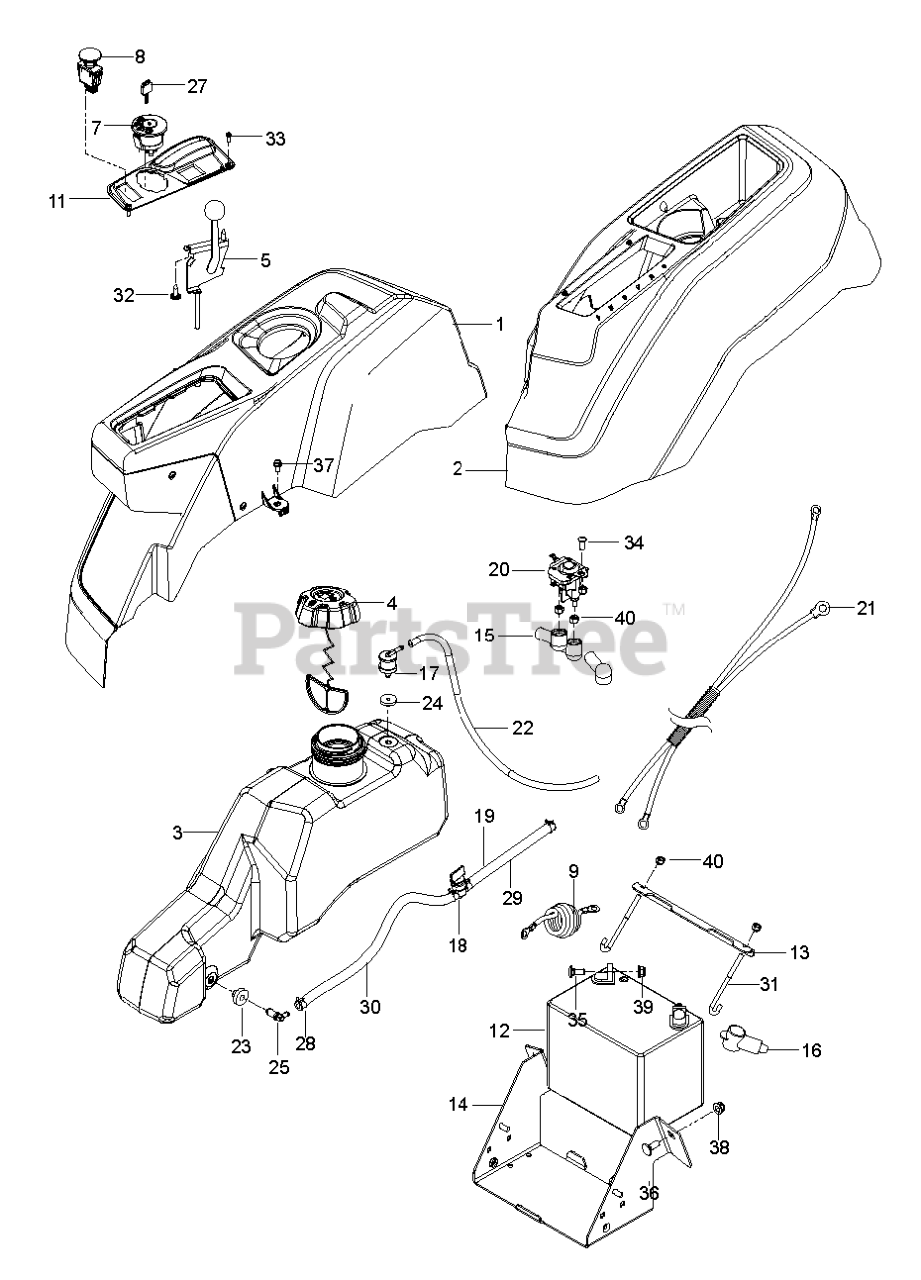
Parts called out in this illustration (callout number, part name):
1	CONSOLE ASM
2	CONSOLE ASM
3	TANK.ASM3"NECK.NOCAP.NOSHDRZ18
4	CAP ASSY FUEL 3" GRAY
5	CABLE.THROTTLE.20"
7	RP IGNITION SWITCH
8	RP SWITCH.PTO.TERMINAL.STD.RED
9	CABLE BATTERY POS RZ
12	BATTERY 12 VOLT 25 AMP
13	BRACKET.PNT.MOUNT.BATTERY.EDIP
14	BOX.PNT.BATTERY.RZ.EDIP
15	TERMINAL COVER
17	VALVE.FUEL.CHECK
18	FUEL VALVE
19	FUEL.HOSE.SHUT.OFF.ASM.10".3"
20	SOLENOID.STARTER.BRASS.PLUNGER
21	HARNESS.BTTRY.CABLE.RZ.REFRESH
22	HOSE.3/16".VAPOR.LINE.18"LGTH
23	BUSHING OUTLET T
24	GROMMET.ROV.SENTEC
25	STEM FUEL TANK
26	PLUG.TEX.DASH.SVC.MINDER.GREY
27	KEY.CHAIN.BLISTER.PACK.GEN.USA
28	HOSE CLAMP
29	HOSE.1/4".LOW.PERM.FUEL.LN.3"
30	HOSE.1/4".LOW.PERM.FUEL.LN.10"
31	HOOK.J.BATTERY
32	SCREW.PAN.HEAD.#10
33	SCREW 6-19X.437
34	SCR 1/4-20 X 5/8 BTN SKT HD ZD
35	BOLT 5/16C X 3/4" CARRIAGE
36	RHSNB 3/8C X 1
37	SCREW
38	NUT 3/8-16 HEX FLG NYLOC ZD
39	5/16-18 NYLOC FLANGE NUT
40	NUT.1/4-20.HEX.NYLOC.ZD
